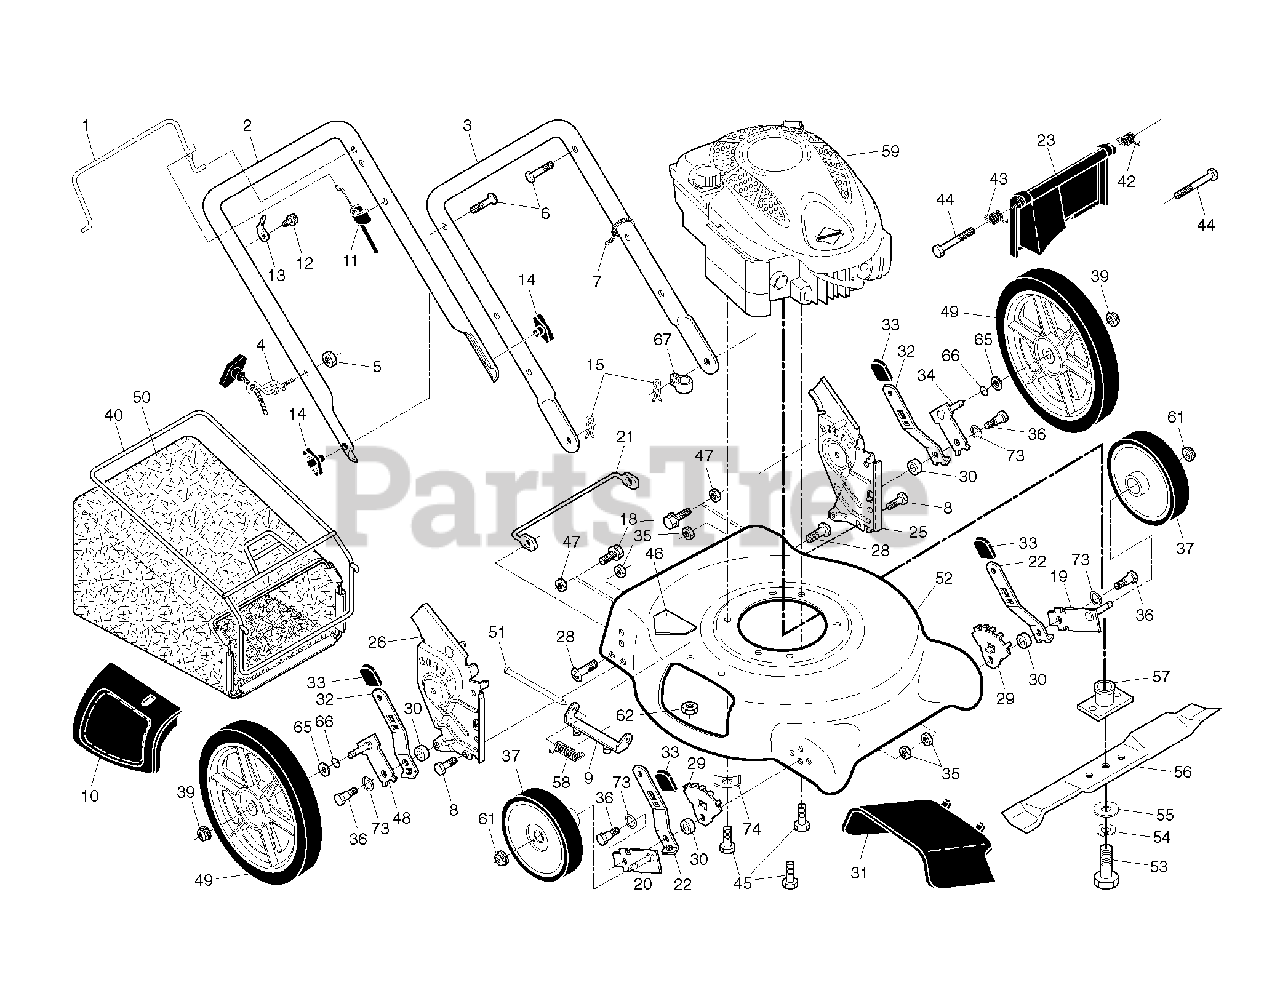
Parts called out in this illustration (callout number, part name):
2	HANDLE.UPPER
3	HANDLE.LOWER.BLACK
4	GUIDE.ROPE.STD.BLK.ZIN
5	NUT
6	BOLT, HANDLE 5/16-18X1.75
7	TIE GUIDE
8	BOLT
9	HINGE BRACKET
10	MULCH DOOR
11	CABLE.ENGINE.ZONE.CONTROL
13	BRACKET.UPSTOP.RT
14	KNOB, DEFLECTOR
15	HAIRPIN COTTER
19	AXLE ARM ASSY FRONT LH
20	AXLE ARM ASSY FRONT RH
22	SELECTOR SPRING, FRONT
23	REAR DOOR ASSY
25	BRACKET.ASM.HAND.HW.21.LT
28	SCREW 14-20 X 5/8
29	WHEEL ADJ BRACKET FRONT
30	SPACER.HEIGHT.ADJUSTER
31	CLIP ON DISCHARGE GUARD
32	SPRING.SEL.EXT.21.DOMED.12/14
33	SELECTOR KNOB
34	AXLE ARM ASSY REAR LH
35	NUT.FLANGE.HEX.5/16X18.BLACK
36	SHOULDER BOLT 5/16-18
39	NUT.HEX.FLANGE.3/8-16.LOCKNUT
40	FRAME.BAG.21.REAR.DOMED.PUSH
42	SPRING.LH.22.REAR.DOOR.EZ.EMPT
43	SPRING.RH.22.REAR.DOOR.EZ.
45	BOLT 3/8-16X1-1/8
46	DECAL.INTERNATIONL.CUTFINGER
48	AXLE ARM ASSY REAR RH
50	GBAG.
51	ROD.HINGE.COMBI-C
53	SCREW, HEX HD 3/8-24 X 1-3/8
54	LOCKWASHER
55	WASHER,HARDEN
56	BLADE.21.PUSH
57	ADAPTER.BLADE.W/KEY.25MM.CE
58	TORSION SPRING
61	NUT.HEX.FLANGE.3/8-16.LOCKNUT
62	LOCKNUT
65	WASHER PM
66	O-RING..070X.487.NEOPRENE
67	CLIP.CABLE.BLK
73	WASHER FLAT
